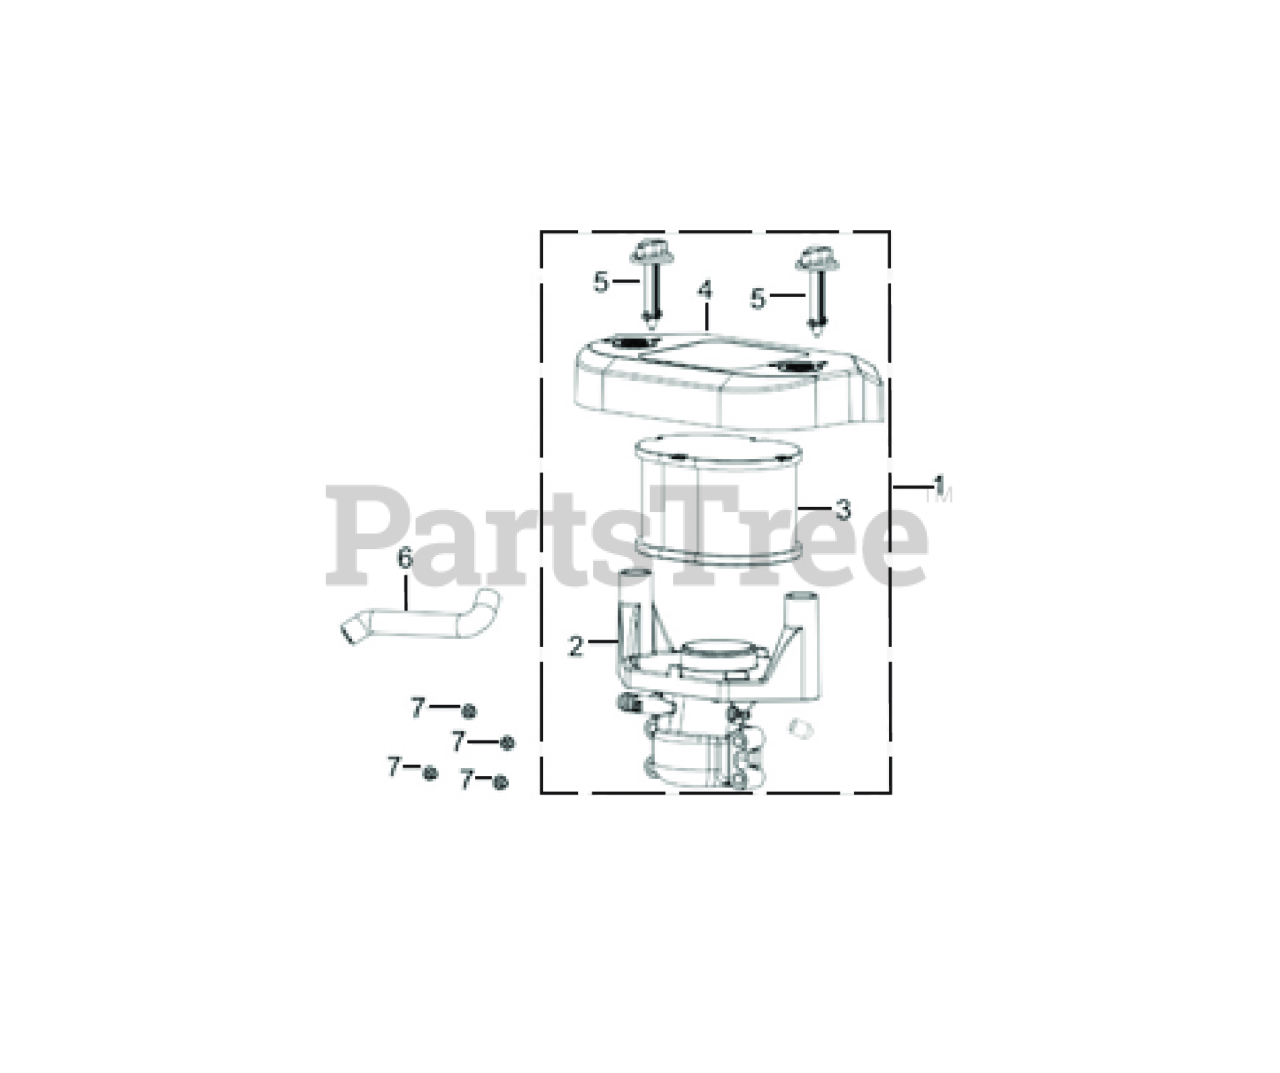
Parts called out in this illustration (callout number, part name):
1	Air Filter Assembly
2	Base, Air Filter
3	Element, Air Filter
4	Cover, Air Filter
6	Tube, Breather
7	Nut, Flange
